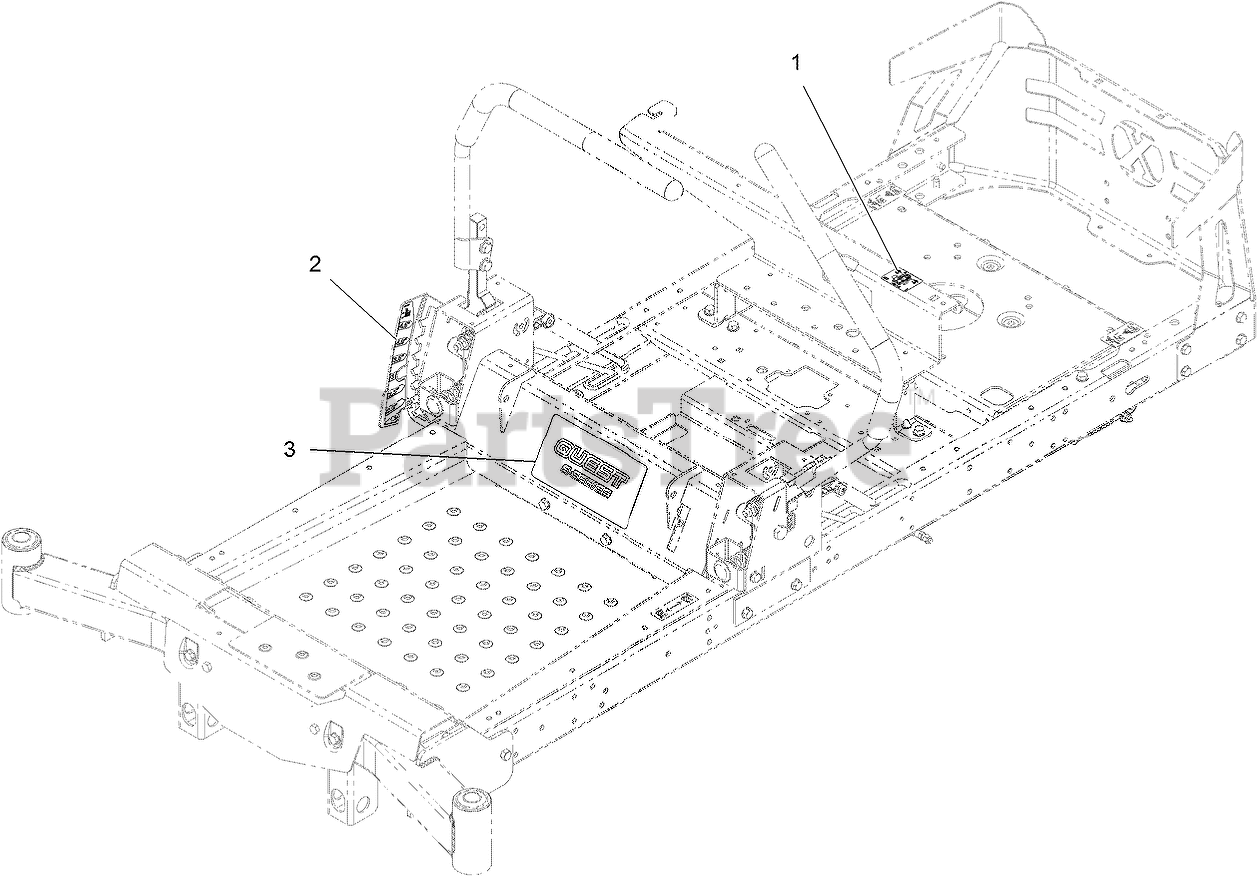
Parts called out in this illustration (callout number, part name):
1	DECAL-SERVICE, CE
2	DECAL-HOC
3	DECAL, QUEST S SERIES
